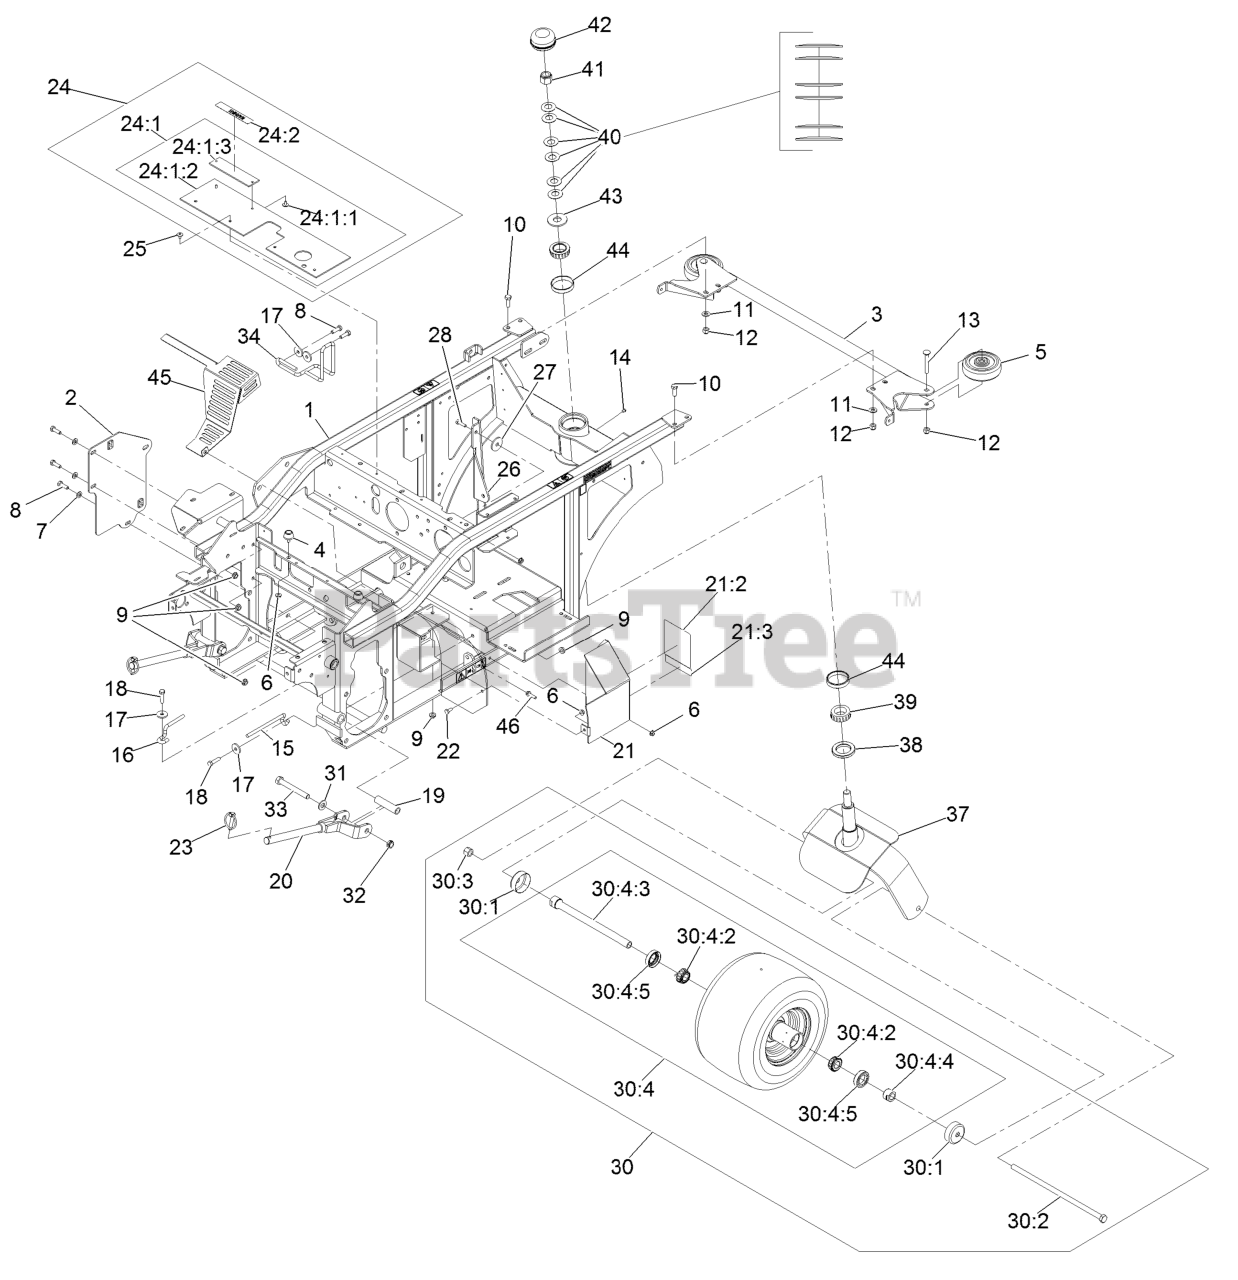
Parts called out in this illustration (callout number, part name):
1	FRAME ASM
2	PLATE-SUPPORT
3	BUMPER-REAR
4	BUMPER-RUBBER
5	ROLLER-BUMPER
7	WASHER-PLAIN
8	SCREW-HH
10	SCREW-HH
11	WASHER-FLAT
12	NUT-LOCK, NI
13	SCREW-CARR
15	GUIDE-BELT
16	GUIDE-BELT
18	SCREW-HH
19	SPACER-WHEEL, SHORT
21	DRIVE SHIELD ASM
21:2	Decal-Belt Routing
21:3	DECAL-WARNING
22	SCREW-HH
23	PIN-LYNCH
24	LIFT SHIELD ASM
24:1	Shield-Lift
24:1:1	RIVET-POP
24:1:3	Plate-Decal
24:2	DECAL-WARNING
25	RIVET-POP
26	BRACE-PTO
28	SCREW-HH
30	REAR CASTER WHEEL ASM
30:1	GUARD-SEAL
30:2	SCREW-HH
30:3	NUT-LOCK, NI
30:4	ASM,WHEEL,TIRE & BRG SP
30:4:2	BEARING-CONE, TAPERED ROLLER
30:4:3	AXLE CASTER ASM
30:4:4	SPACER-NUT
30:4:5	SEAL-CASTER
31	WASHER-FLAT
32	NUT-HEX
33	SCREW-HH
34	GUIDE-BELT
37	FORK-REAR CASTER
38	SEAL-GREASE
39	BEARING-ROLLER, CONE TAPE
40	WASHER-BELLVILLE
41	NUT-LOCK, NI
42	CAP-GREASE
43	WASHER-FLAT
44	CUP-TAPERED, ROLLER BEARI
45	SHIELD-HEAT
46	SCREW-HHF
